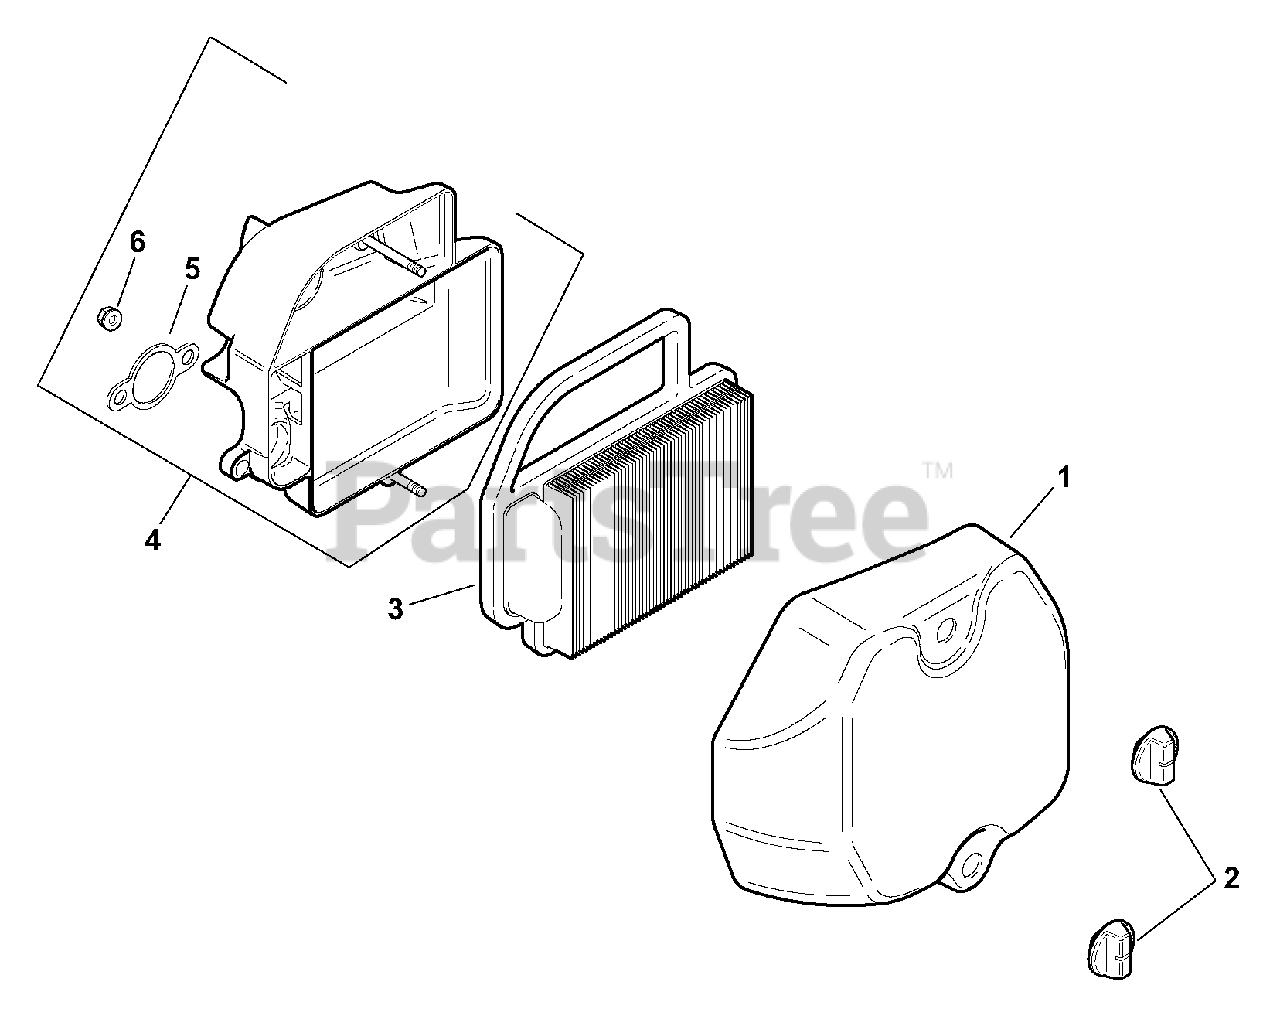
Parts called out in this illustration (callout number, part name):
1	Kit,Air Cleaner Cover
2	Knob, Cover
3	Element, Air Cleaner
4	Kit, Air Cleaner Base
5	Gasket, Air Cleaner Base
6	Nut, Flg M6x1.0
